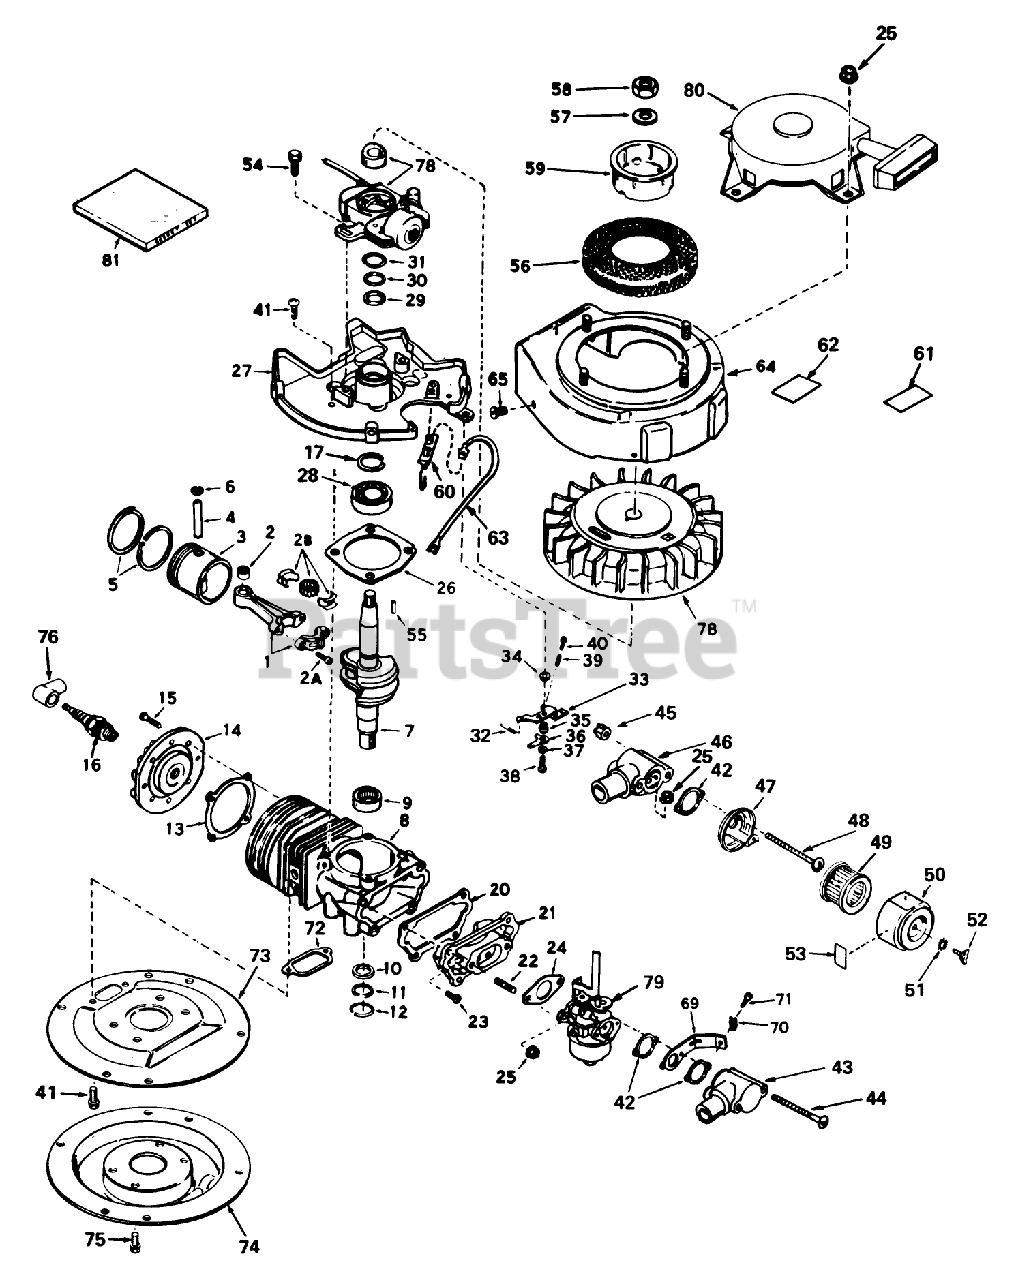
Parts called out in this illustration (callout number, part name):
1	Rod Assy., Connecting (Incl. Nos. 2, 2A 2B)
2	Bearing-Cartridge
2A	Bolt-Rod, Connecting
2B	Needle Bearing and Liner Set (37 Needles)
3	Piston Assy. (Incl. Nos. 4, 5 6)
4	Pin, Piston
5	Ring Set
6	Ring-Retaning
7	Crankshaft
8	Block Assy., Cylinder (Incl. Nos. 9 thru 12)
9	Bearing, Needle
10	Seal, Crankshaft
11	Retainer, Crankshaft Seal
12	Spring, Crankshaft Seal Retainer
13	Gasket, Head
14	Head-Cylinder
15	Screw (T-30, 1/4-20 x 3/4)
16	Plug, Spark (Champion RCJ-8)
17	Ring, Retaining
20	Gasket, Reed Plate
21	Plate Assy., Reed (Incl. No. 22)
22	Stud Carburetor
23	Screw (T-25, 10-24 x 1/2)
24	Gasket, Carburetor
25	Locknut
26	Gasket, Shroud Base
27	Base Assy., Housing (Incl. Nos. 29, 30 31)
28	Bearing-Ball
29	Seal, Crankshaft
30	Retainer, Crankshaft Seal
31	Spring, Crankshaft Seal Retainer
32	Spring, Governor
33	Lever, Control
34	Washer
35	Spacer
36	Lever, Adjusting
37	Washer
38	Screw, Pan Flex Hd.
39	Spring-Compression
40	Screw
41	Screw
42	Gasket
43	Elbow, Carburetor
44	Screw, Rd. Hd. Mach.
45	Nut-Lock
46	Elbow
47	Air Cleaner Pan
48	Screw
49	Air Cleaner Element
50	Air Cleaner Cover
51	Washer-Lock
52	Wing Screw
53	Air Cleaner Decal
54	Screw, Hex Washer Hd.
55	Key-Flywheel
56	Screen, Air
57	Washer-Spring
58	Nut-Flywheel
59	Starter Cup
60	Terminal
61	Decal, Warning
62	Decal, Fuel Mix
63	Wire, Ground
64	Housing, Blower
65	Screw-Hex, Hd.
69	Bracket, Boden Wire
70	Conduit
71	Screw (10-32 x 3/8)
72	Gasket, Exhaust
73	Ring, Adapter
74	Muffler
75	Screw, Flanged Hex Hd.
76	Cover-Spark Plug
78	Magneto
79	Carburetor (Incl. No. 24)
80	Starter, Rewind
81	Gasket Set
